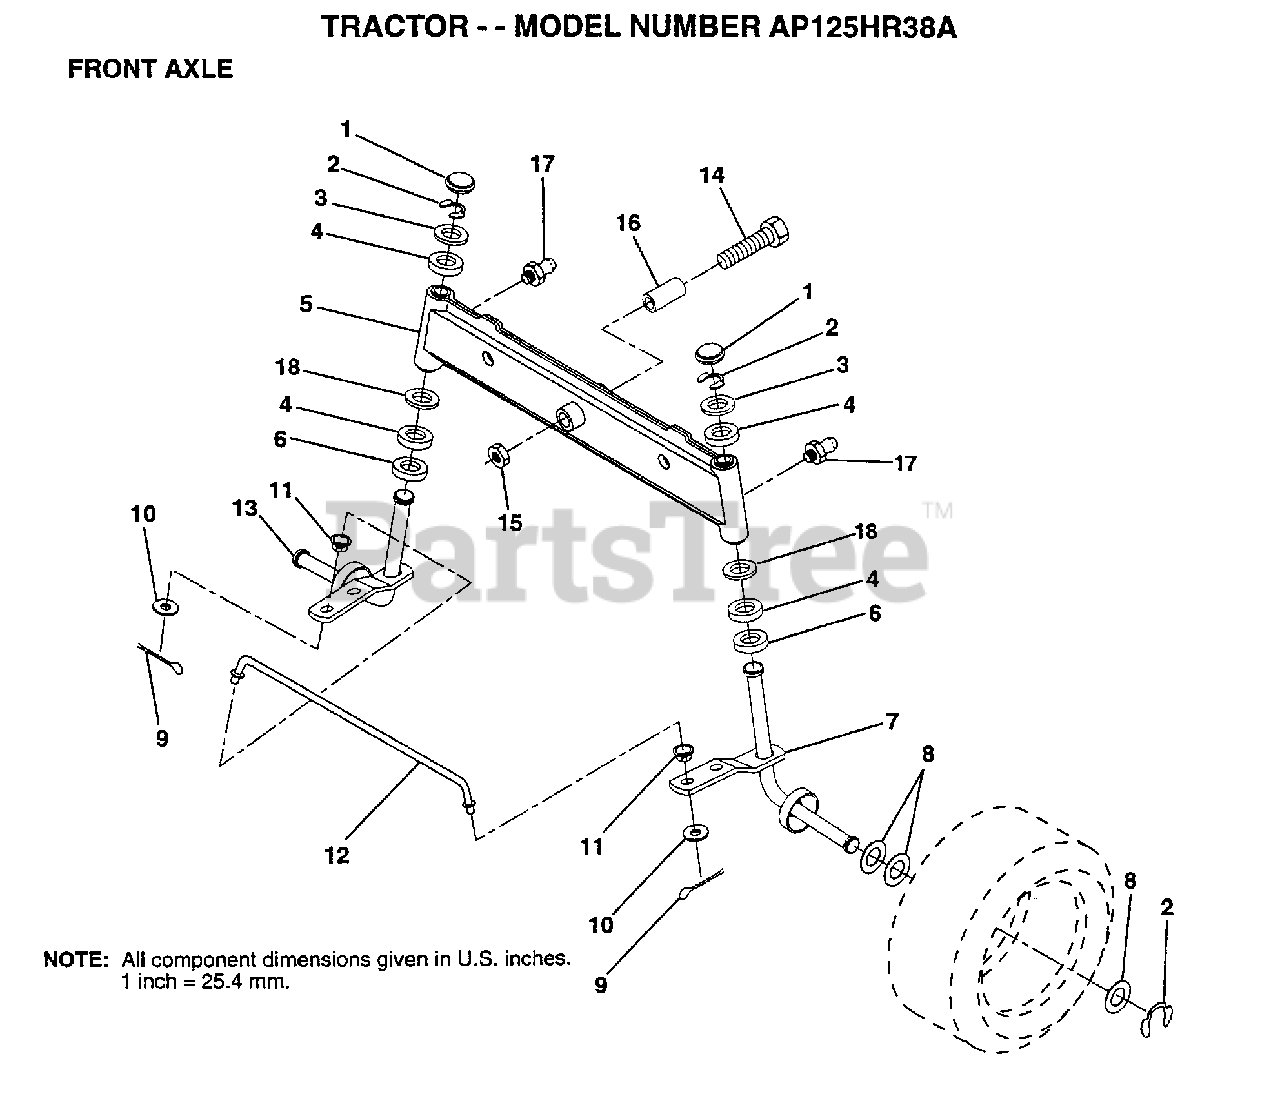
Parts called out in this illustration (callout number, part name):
1	CAP
2	RING
3	WASHER
4	COL. SRTG. BEAR.
5	AXLE ASM FRONT
6	WASHER .T
7	SPINDLE ASM RH
8	WASHER
9	COTTER PIN
10	WASHER
11	BUSHING.DRAGLINK
12	TIE ROD
13	SPINDLE ASM LH
14	BOLT HEX 5/8-11
15	"NUT-LOC,FLANGE LT"
16	BEARING
17	ZERK M
18	WASHER
